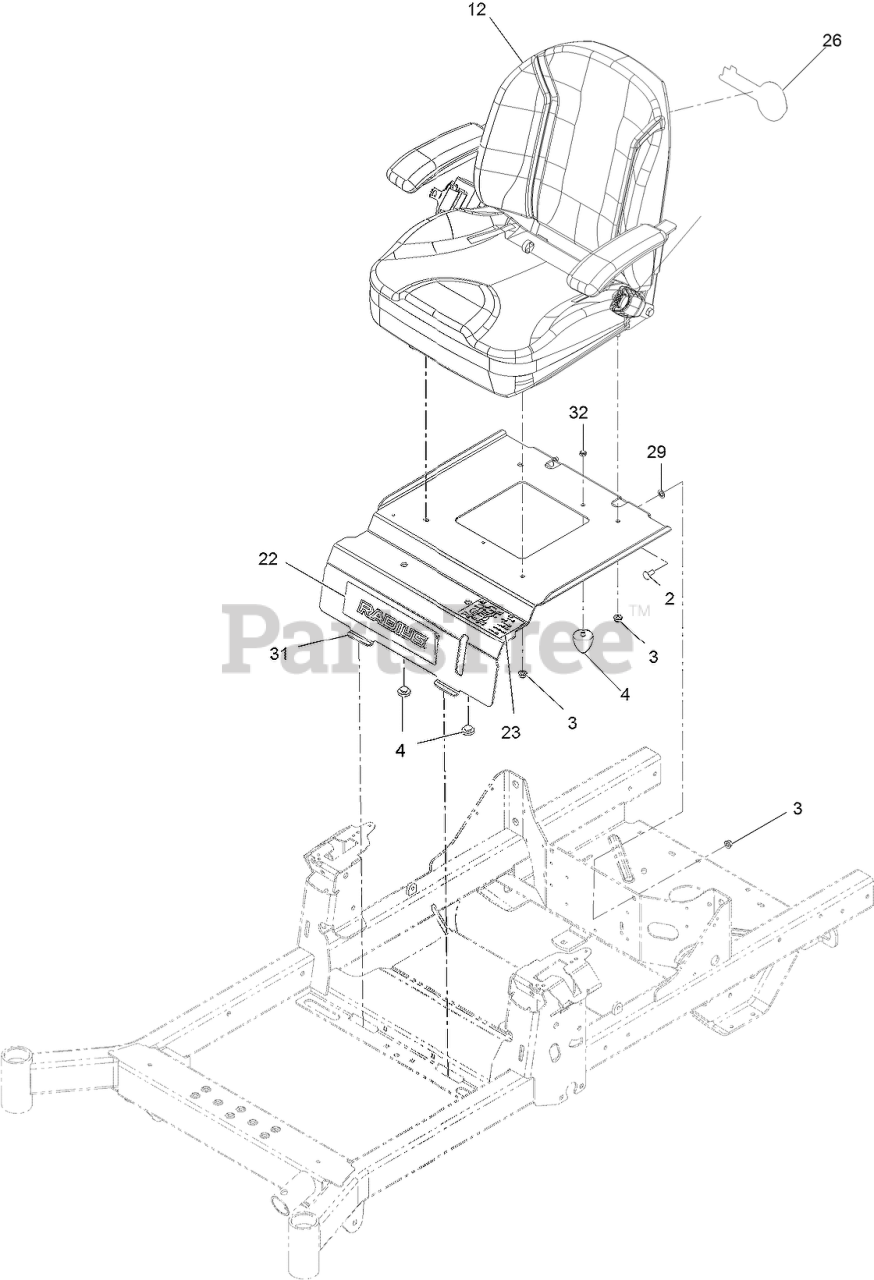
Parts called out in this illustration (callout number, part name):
2	SCREW-CARR
3	NUT-HF, NI
4	BUMPER-SEAT
4	BUMPER-RUBBER
12	ASM-SEAT EXMARK
22	DECAL-RADIUS LOGO
23	DECAL-AID, SERVICE
26	DECAL, EXMARK LOGO
29	Washer-Retaining
31	PLATE-FIXED SEAT
32	NUT-LOCK, NI
